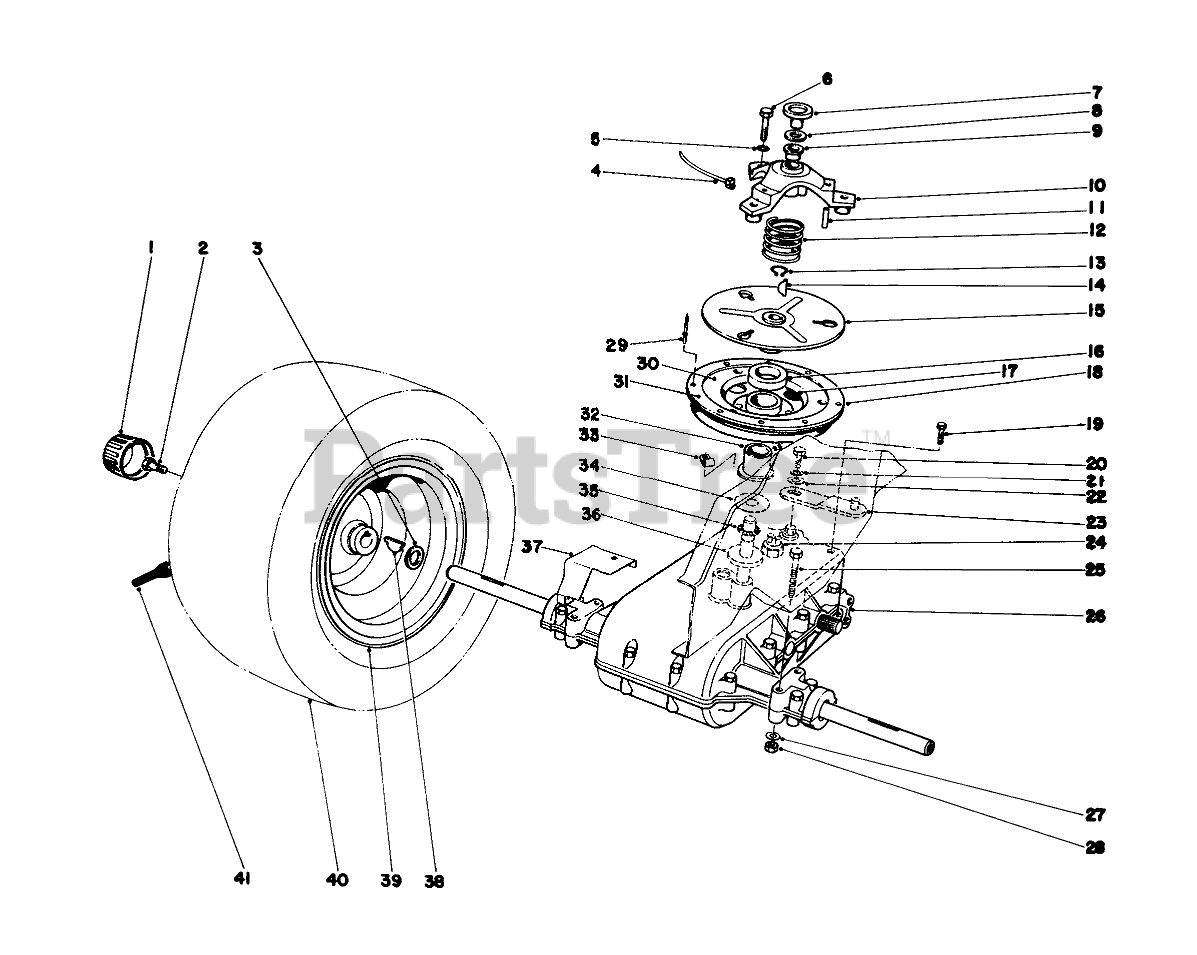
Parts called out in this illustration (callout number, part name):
1	Cap-Hub
2	CAPSCREW 3/8 16 3/4
3	SPACER-WHEEL
4	TIE-MOUNT, PUSH
5	WASHER-LOCK
6	SCREW-HH
7	CLUTCH CAP
8	THRUST RACE
9	BUSHING-FLANGE
10	Cover Clutch (Incl. Ref. #9 & 11)
11	NEEDLE BRG
12	COMPRESSION SPRING
13	RING-SNAP, EXTERNAL
14	KEY-WOODRUFF
15	Clutch Plate
16	WASHER FELT
18	Sheave Assembly (Incl. Ref. #29-32)
19	SCREW-HWHTF
20	SCREW-HH
21	WASHER-LOCK
22	WASHER-FLAT
23	SHIFT LEVER WA B
24	NEUTRAL SWITCH
25	SCREW-HH
26	Transaxle
27	WASHER-PLAIN
28	NUT-LOCK, CONE
29	RIVET-POP
30	RETAINER RING R
31	CLUTCH PAD
33	CLIP-FUEL LINE
34	THRUST WASHER
35	NEEDLE BRG
36	SPACER
37	GRASS SHIELD B
39	Rim
41	STEM-VALVE
